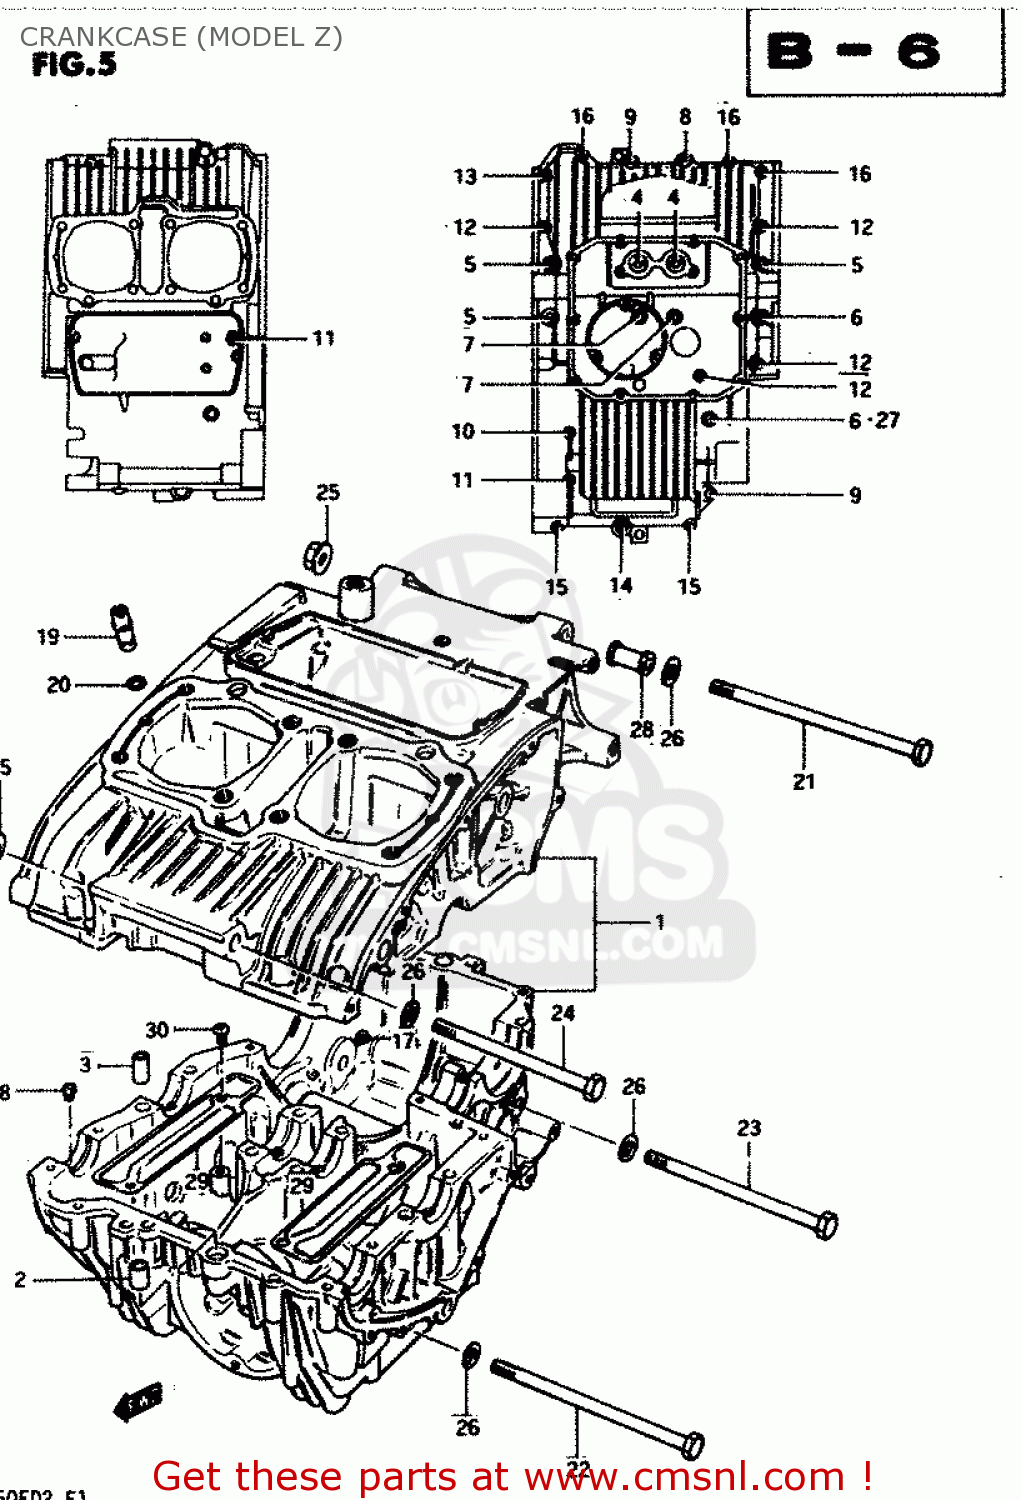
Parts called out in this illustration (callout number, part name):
1	CRANKCASE ASSEMBLY
2	PIN(10.4X13X22)
3	PIN (11X20)(SUS)
4	BOLT
5	BOLT
6	BOLT
7	BOLT
8	BOLT 8X65
9	BOLT (8X45)
10	BOLT(6X125)
11	BOLT(6X105)
12	BOLT (6X90)
13	BOLT (6X70)
14	BOLT ,6X50
15	BOLT ,6X50
16	BOLT,UNDER
17	JET,AIR
18	JET
19	JET
20	O RING(D:1.05,ID:3.1)
21	BOLT 10X215
22	BOLT(10X210)
23	BOLT 10X160
24	BOLT
25	NUT 10MM
26	WASHER
27	GASKET 8.2X14X1 (NAS)
28	SPACER,ENGINE MOUNT
29	PLATE,OIL SEPARATOR
30	SCREW
